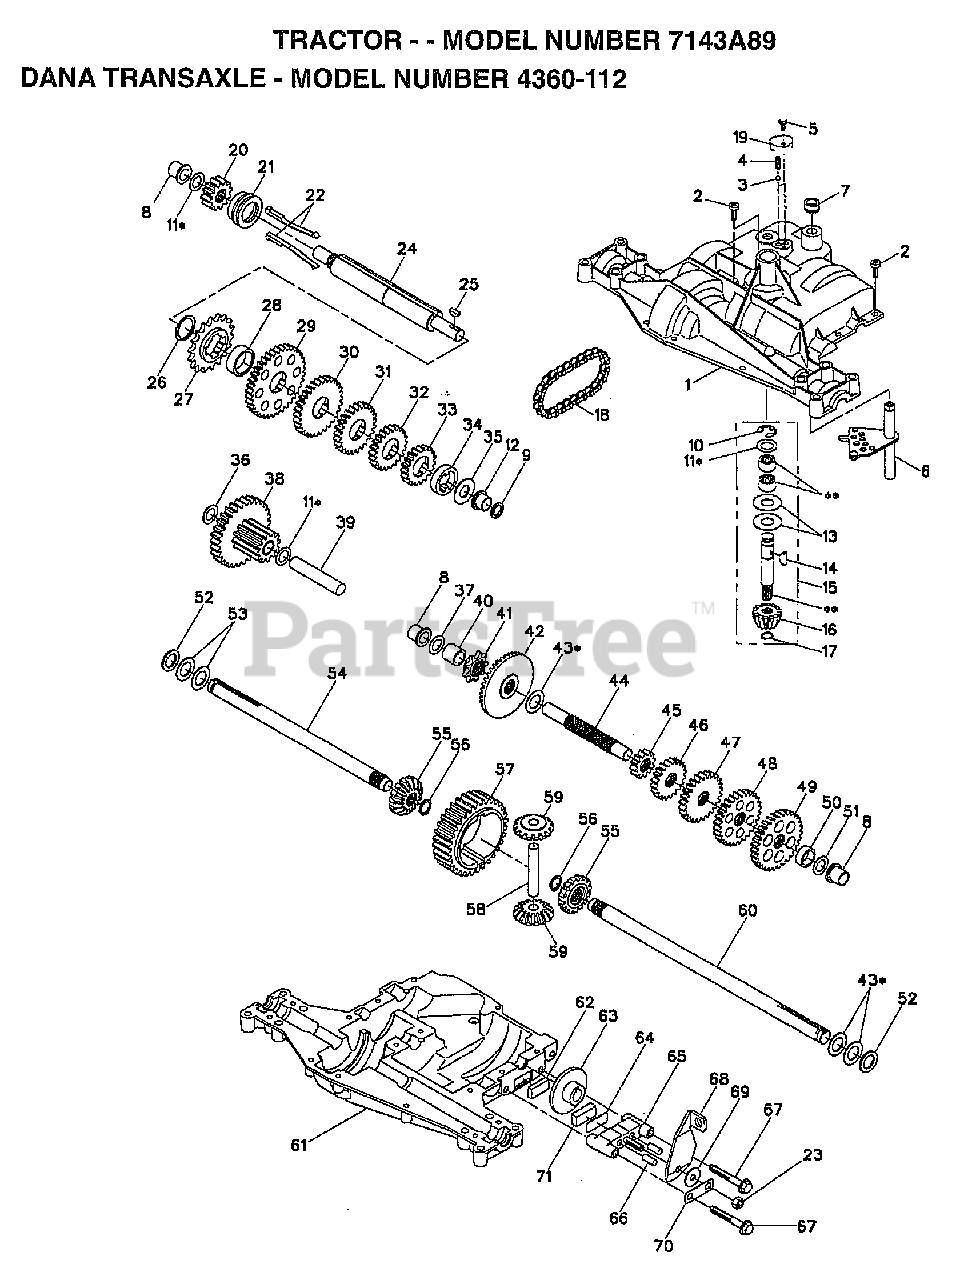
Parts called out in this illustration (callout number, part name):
1	HOUSING.UPPER.DANA.(5305J)
4	"SPRING, DETENT LT"
5	SCREW.TAPPING.1/4-20X.734
6	KIT SHIFTER ASM
9	SEAL.OIL.DAN.5508
10	RETAINING RING LT
11	ASM KIT SHIM 4689
12	BEARING.FLNG.5511
13	WASHER T
14	KEY WOODRUFF-DANA
15	AS KIT INPUT SHFT
16	PINION 14T T
17	"RING,RETAINING LT"
18	"CHAIN,24 PTCH LT"
19	COVER.DETENT.(5584)
20	GEAR.SPUR.12T.(5627)
21	CLUTCH.COL.5467
22	ASM KIT CLTCH KEY
23	NUT.LOCK.5/16-24
24	SHAFT INTERM DANA
25	WOODRUFF KEY
26	"RING,RETAINING LT"
27	SPROCKET 18T T
28	SPACER YT
29	GEAR SPUR 37 TTH
30	GEAR SPUR 30T
31	GEAR 25T LT
32	GEAR SPUR 22 TT
33	SPUR GEAR 19T
34	SPACER
35	"WASHER, PLAIN LT"
36	WASHER 045
37	WASHER 031
38	ASSY.GEAR.6153 12T&30T
39	SHAFT IDLER
40	SPACER T
41	SPROCKET 9T LT
43	ASM KIT SHIM
44	SHAFT T
45	GEAR SPUR 12 TTH
46	GEAR SPUR 20T
47	"GEAR, SPUR 25T LT"
48	GEAR 28T T
49	"GEAR, SPUR 31T LT"
51	WASHER 060
52	NEOPRENE WASHER
53	WASHER 031
54	AXLE.LH(5528-1)
55	GEAR 15T T
56	RING.RETAINING.(5270)
58	SHAFT T
59	GEAR 1ST T
60	AXLE.RH.(5528-2) DANA
61	HOUSING LOWER TNS
62	PUCK T
63	BRAKE DISC. T
64	SPACER LT
66	PIN T
67	SCREW.(5562) .5/16-18X2.35
69	WASHER LT
70	BRACKET, ANTI-ROTATION
71	PUCK T
